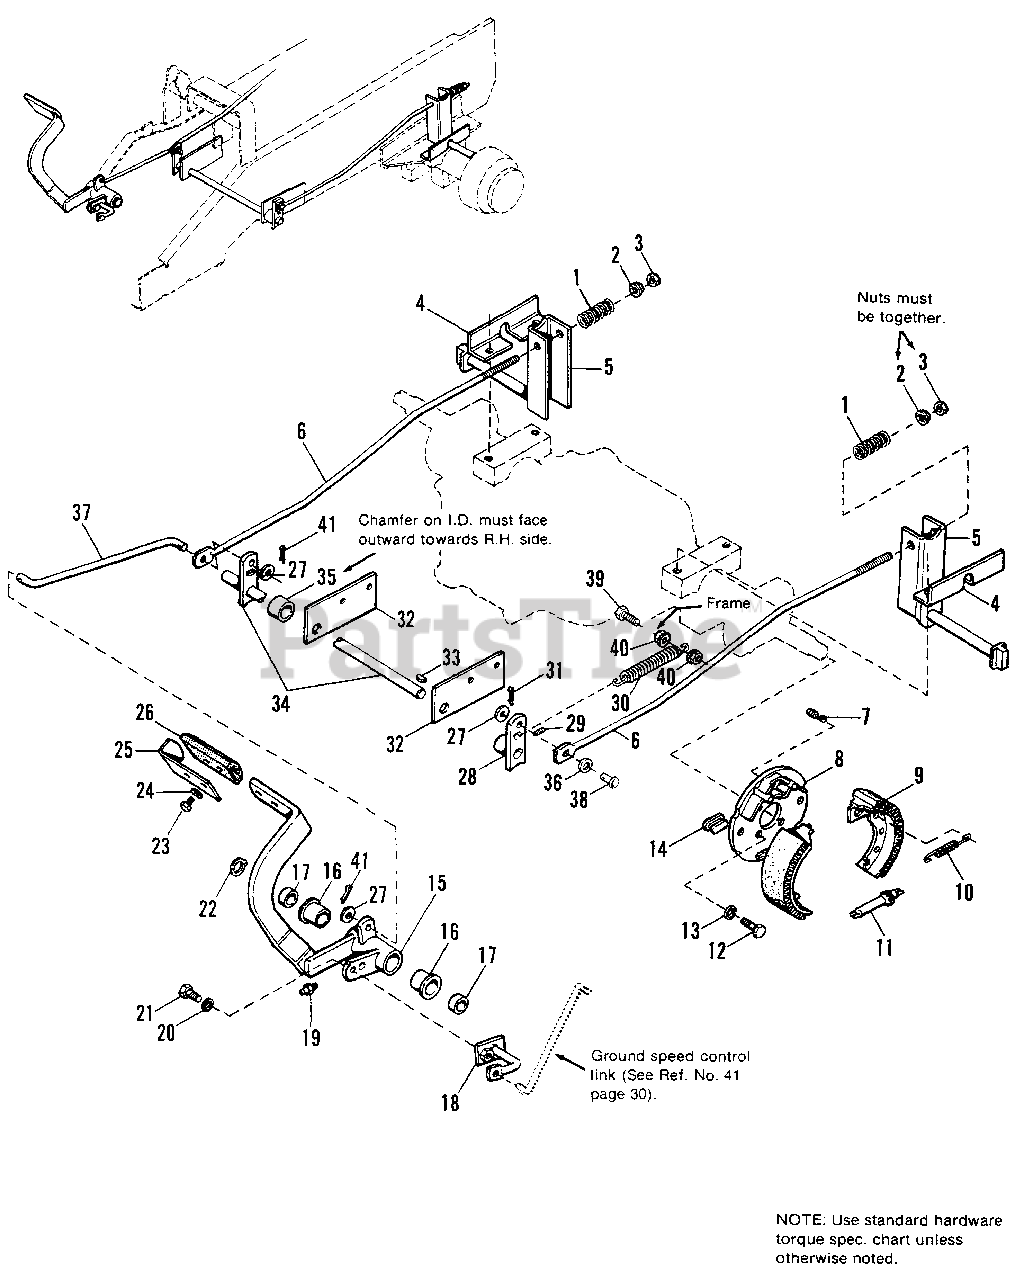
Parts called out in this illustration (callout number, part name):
1	SPRING, Compression
2	NUT, Large Flange, 1/2-13
3	NUT, Hex, 1/2-13
4	SUPPORT, Actuator
5	ACTUATOR ASSY.
6	ROD ASSY. (Incl. Ref. Nos. 36 & 38)
7	SPRING, Extension
8	BRAKE SUPPORT ASSY.
9	BRAKE SHOE & PAD ASSY.
10	SPRING, Extension
11	SCREW ASSY., Brake Adjusting
12	CAPSCREW, Hex Hd., 3/8-16 x 1
13	LOCKWASHER, 3/8
15	LEVER ASSY., Brake, L.H.
16	BUSHING, 1-1/4 x 1-3/4 x 1
18	ROD & PLATE ASSY. Lock
19	FITTING, Lube, 1/4" Drive
20	LOCKWASHER, 5/16
21	CAPSCREW, Hex Hd., 5/16-18 x 3/4
22	RING, Retaining
23	CAPSCREW, Hex Hd., 1/4-20 x 3/4
24	LOCKWASHER, 1/4
25	SUPPORT, Pedal
27	WASHER, Plain, 13/32 x 7/8 X 5/64
28	LEVER ASSY., Brake
29	SETSCREW, Sq. Hd., 5/16-18 x 1/2
30	SPRING, Extension
31	PIN, Cotter, 3/32 x 3/4
32	SUPPORT, Brake Cross Shaft
33	KEY, Woodruff #9
34	SHAFT ASSY., Brake Pivot
35	SPACER, Special
36	WASHER
38	PIN, Brake Rod
39	CAPSCREW, Hex, 5/16-18 x 1-1/4
40	NUT, Hex, Flange Lock, 5 / 16-18
41	PIN, Cotter, 1/8 x 3/4
